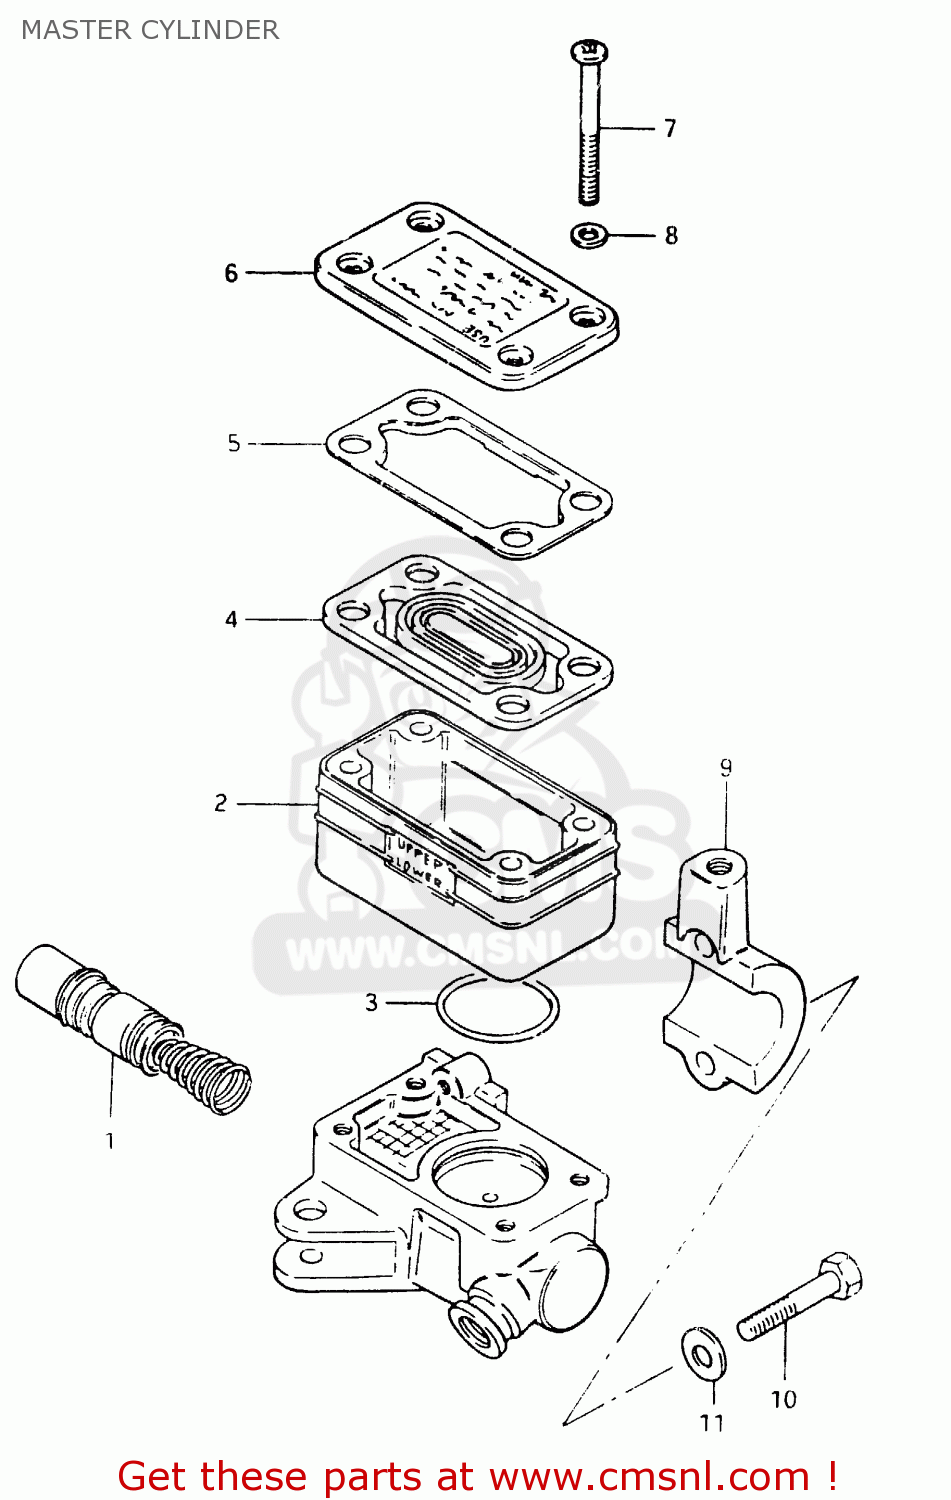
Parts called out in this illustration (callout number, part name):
1	PISTON & CUP SET
2	RESERVOIR
3	O RING
4	DIAPHRAGM
5	PLATE,DIAPHRAGM
6	CAP
7	SCREW
8	WASHER
9	HOLDER
10	BOLT
11	WASHER
